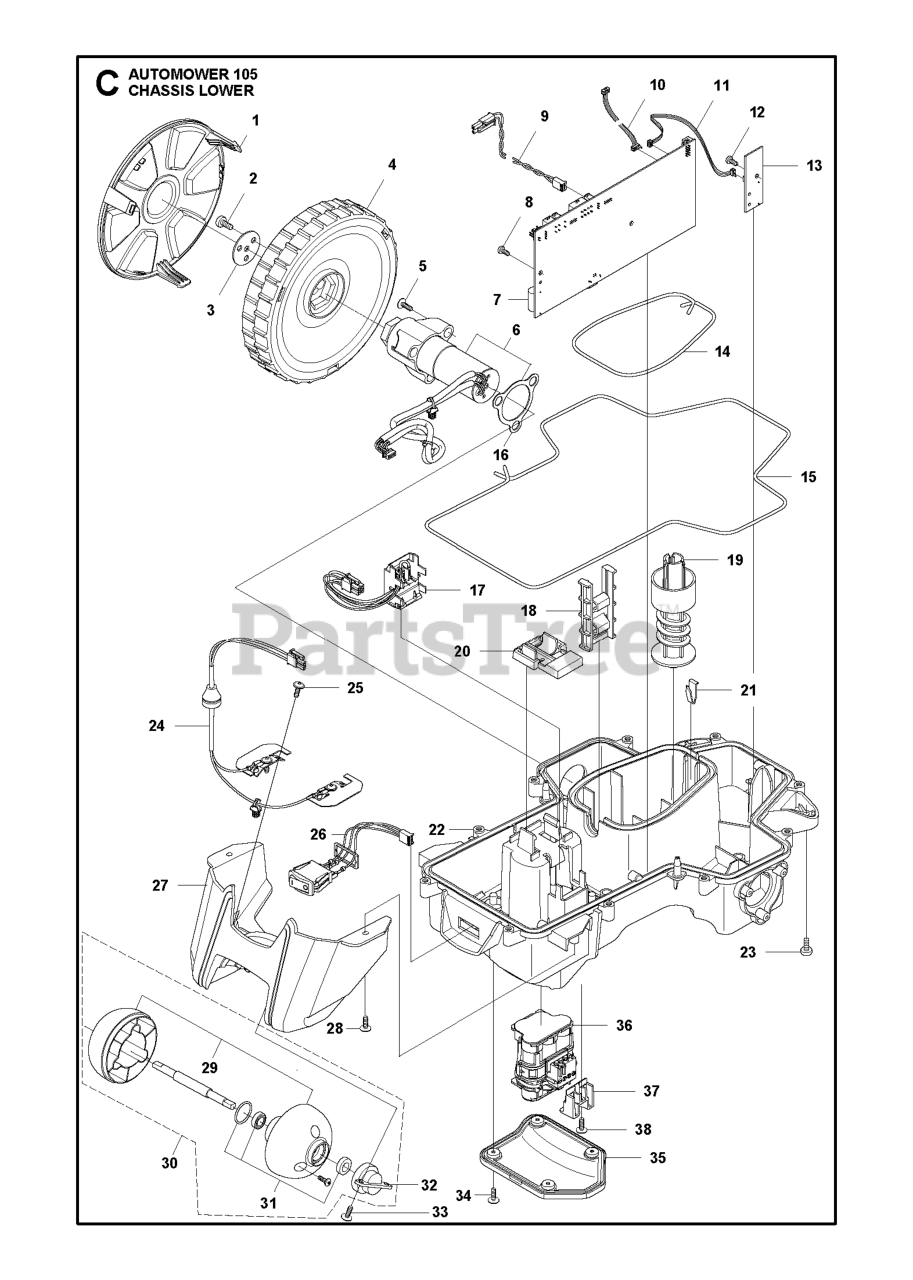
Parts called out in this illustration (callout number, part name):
2	SCREW ITXPANM M5X12 8.8 ZP-BC
3	WASHER DRIVE WHEEL
4	WHEEL DRIVE WHEEL
5	SCREW 14MM
6	WHEEL MOTOR ASSY WHEEL MOTOR K
7	PRINTED CIRCUIT ASSY MAIN BOAR
8	SCREW
9	LOOM BUZZER EXTENSION
10	WIRING ASSY HMI
11	WIRING ASSY LOOP AND LIFT SENS
12	SCREW
13	PRINTED CIRCUIT ASSY SENSOR BO
14	SEALING STRIP P1
15	SEALING STRIP P1 CHASSIS
16	GASKET MOTOR FLANGE
17	LOOM BATTERY 18 V LLITHIUM
18	GUIDE RAIL MOTOR BOWL
19	SCREW HEIGHT ADJUSTMENT
20	LOCK BATTERY PLUG
21	LOCKING SPRING
22	CHASSIS CHASSIS LOWER KIT INCL
23	SCREW ITXPANM M5X12 8.8 ZP-BC
26	LOOM ON/ OFF
27	HOUSING REAR WHEEL FLAME RETAR
28	SCREW 14MM
29	REAR WHEEL REAR WHEEL KIT, LEF
30	REAR WHEEL REAR WHEEL KIT COMP
31	REAR WHEEL BEARING AND SEALING
32	BEARING HOUSING REAR WHEEL
33	SCREW 14MM
34	SCREW ITXPANT
35	COVER BATTERY
36	BATTERY LI-ION
37	BRACKET BATTERY HOLDER
38	SCREW 14MM
